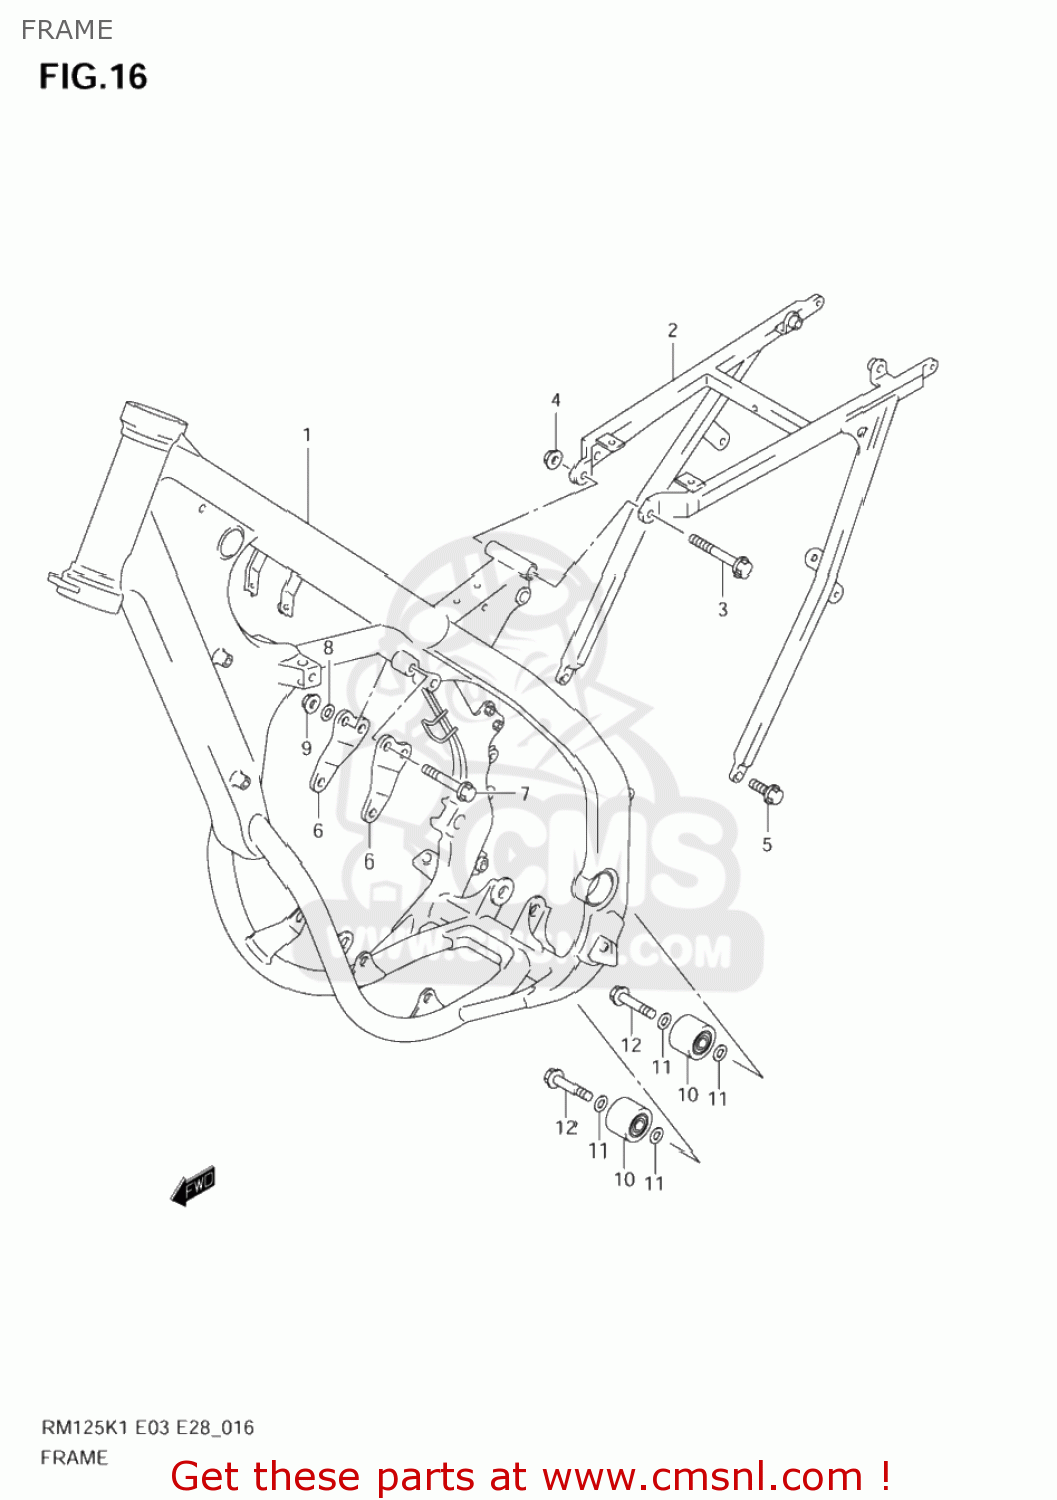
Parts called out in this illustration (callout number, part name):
1	FRAME(SILVER)
2	RAIL,SEAT
3	BOLT(8X100)
4	NUT
5	BOLT(8X16)
6	PLATE,ENG MTG UPR
7	BOLT(8X45)
8	WASHER
9	NUT
10	ROLLER,CHAIN
11	SHIM(8X12X1)
12	BOLT(8X41)
